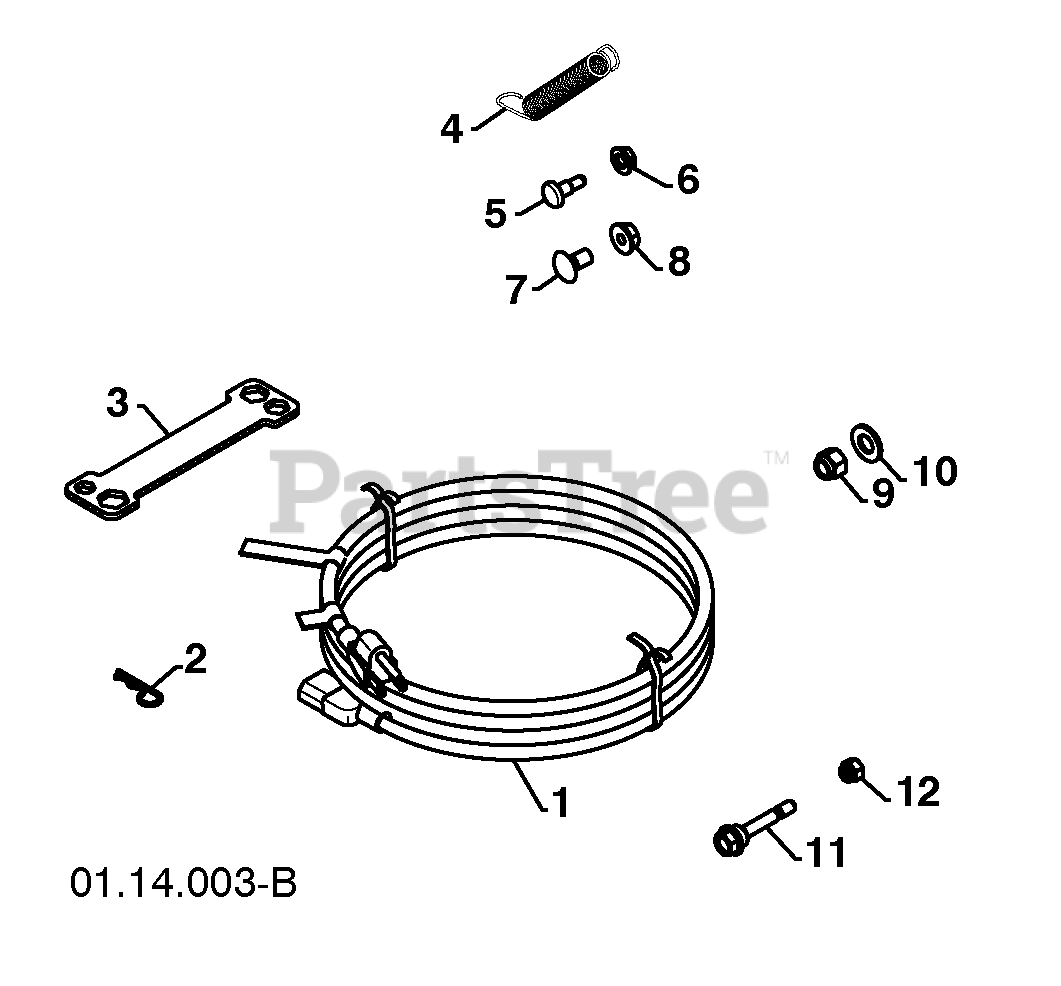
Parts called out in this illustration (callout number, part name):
1	POWER CORD
2	RETAINER PIN
3	WRENCH
4	REMOTE SPRING
5	SHOULDER BOLT 1/4-20
6	LOCKNUT 1/4-20
7	CARRIAGE BOLT 5/16-18 X 5/8
8	LOCKNUT 5/16-18
9	LOCKNUT 3/8-16
10	WASHER 3/8
11	SHEAR BOLT 1/4-20 X 1-13/16
12	LOCKNUT 1/4-20
